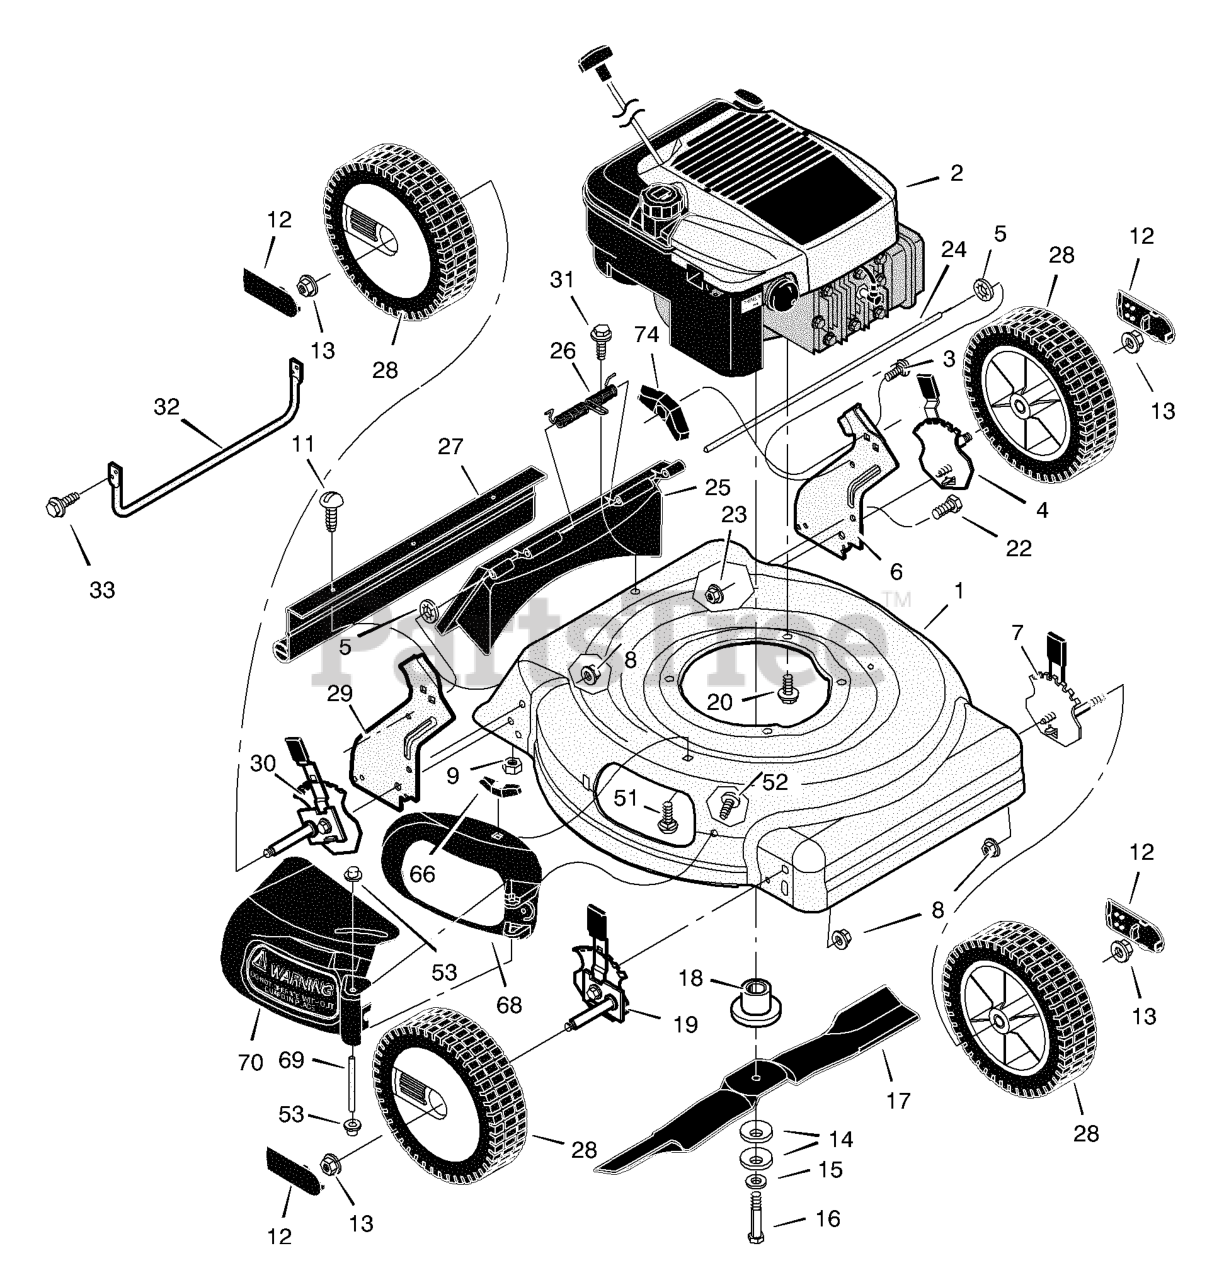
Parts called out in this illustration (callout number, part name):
1	Housing
2	Engine *
3	Bolt, Carriage
4	Adjuster, Left Rear Height
5	Push Retainer
6	Bracket, Left Handle
7	Adjuster, Left Front Height
8	Nut, Flange
9	Nut, Hex
12	Hub Cap
13	Nut, Flange
14	Washer, Belleville
18	Adapter, Blade
19	Adjuster, Right Front Height
20	Bolt, Engine
22	Bolt
23	Nut, Flange
24	Rod, Pivot
25	Door, Rear
26	Spring
27	Guard, Rear
29	Bracket, Right Handle
30	Adjuster, Right Rear Height
32	Guard, Rear
33	Screw
51	Bolt, Carriage
53	Push On Cap
66	Wingnut
68	Bezel (Black)
69	Pin, Pivot
70	Deflector, Chute (Black)
